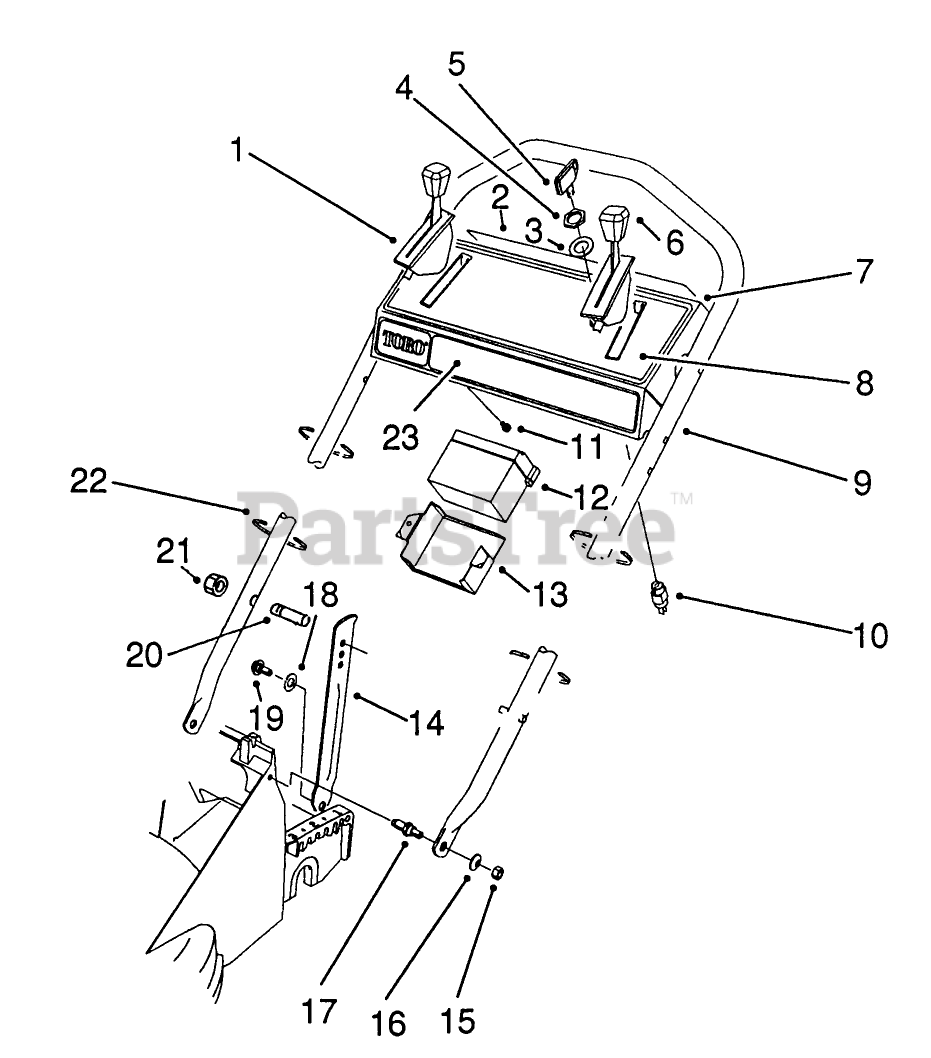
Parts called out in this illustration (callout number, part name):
2	DECAL-PANEL, DANGER
3	WASHER-LOCK
4	NUT-HH
5	KEY-IGNITION
7	PANEL W/ DECAL ASM
10	STARTER SWITCH ASM
11	SCREW-HWHTF
13	BATTERY ASSEMBLY,WET
15	NUT-LOCK, NI
16	WASHER-PLAIN
19	SCREW-SHOULDER
20	HANDLE PIN
21	NUT-LOCK, NI
22	TIE-CABLE
